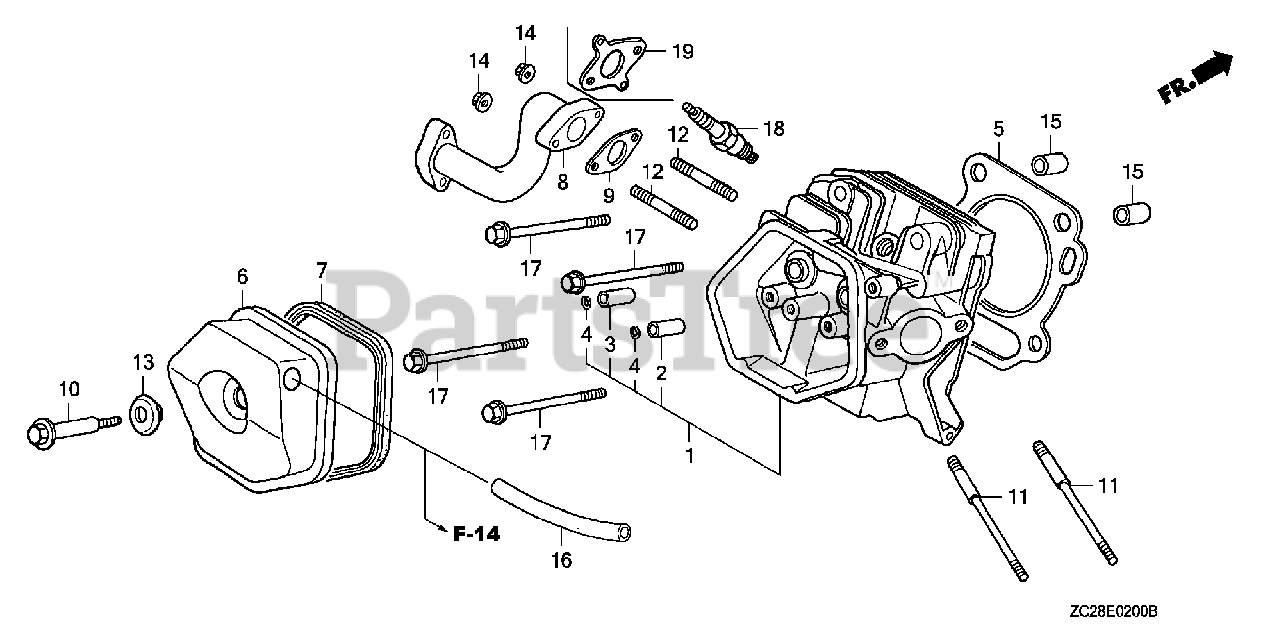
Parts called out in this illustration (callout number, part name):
1	CYLINDER HEAD
2	GUIDE, VALVE (OS)
3	GUIDE, EX. VALVE (OS)
4	CLIP, VALVE GUIDE
5	GASKET, CYLINDER HEAD
6	COVER KIT, HEAD
7	GASKET, CYLINDER HEAD COVER
9	GASKET, EX. PIPE
9	GASKET, EX. PIPE (WACKER)
10	BOLT, HEAD COVER
11	BOLT, STUD (8X106)
12	BOLT 2, STUD (8X32)
13	WASHER, HEAD COVER
14	NUT, FLANGE (8MM)
15	PIN A, DOWEL (12X20)
16	BULK HOSE, VACUUM (11X1000) (11X105)
17	BOLT, FLANGE (10X80)
18	SPARK PLUG (BPR5ES-11) (NGK) Use up to Engine SN 1253117.
18	SPARK PLUG (W16EPR-U11) Use up to Engine SN 1253117.
18	SPARK PLUG (BPR5ES) (NGK)
18	SPARK PLUG (W16EPR-U) (DENSO)
18	SPARK PLUG (BPR6ES-11) (NGK)
18	SPARK PLUG (W20EPR-U11) (DENSO)
